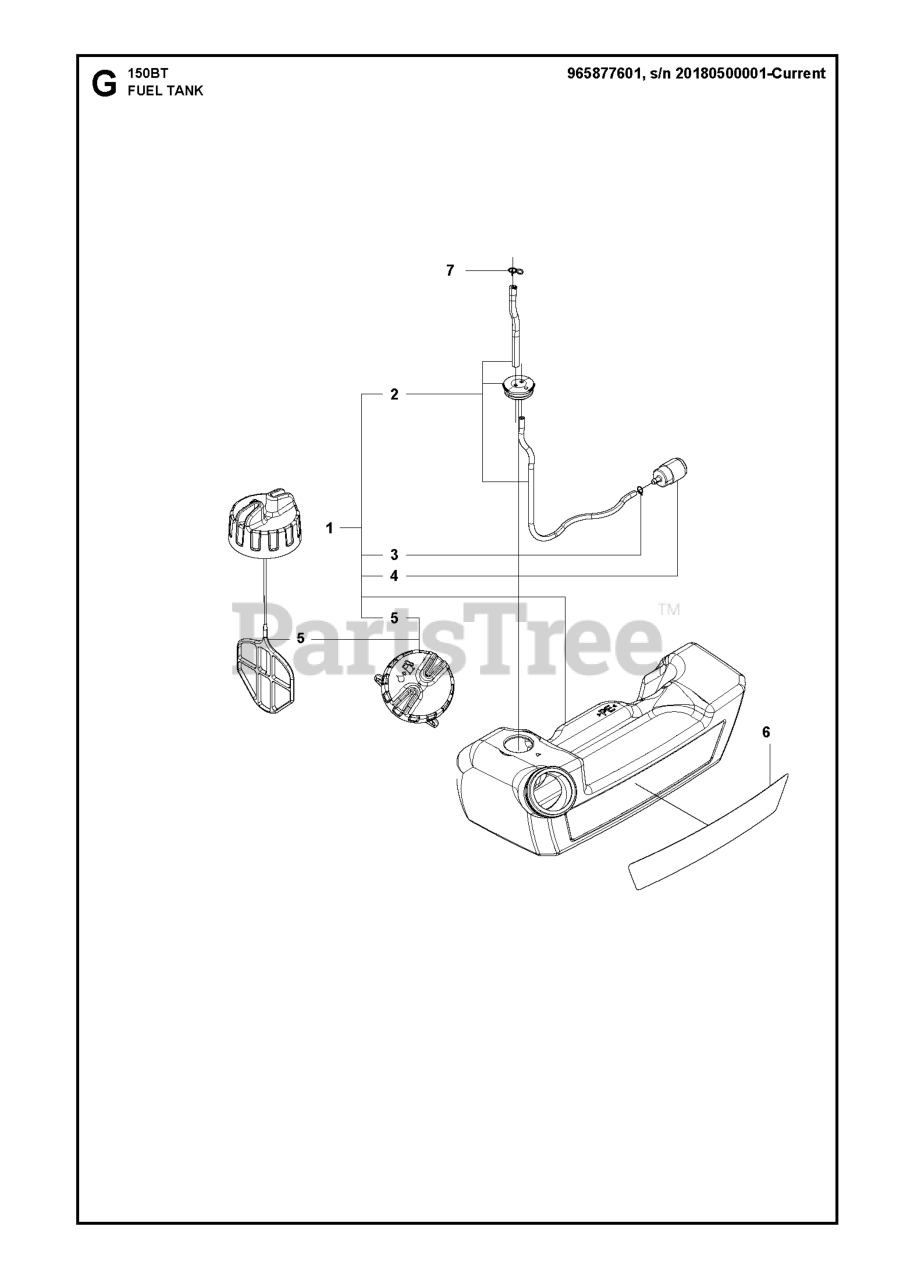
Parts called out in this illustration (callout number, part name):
1	FUEL TANK ASSY
2	Fuel Hoses
4	RP FUEL FILTER
5	FUEL CAP ASSY
